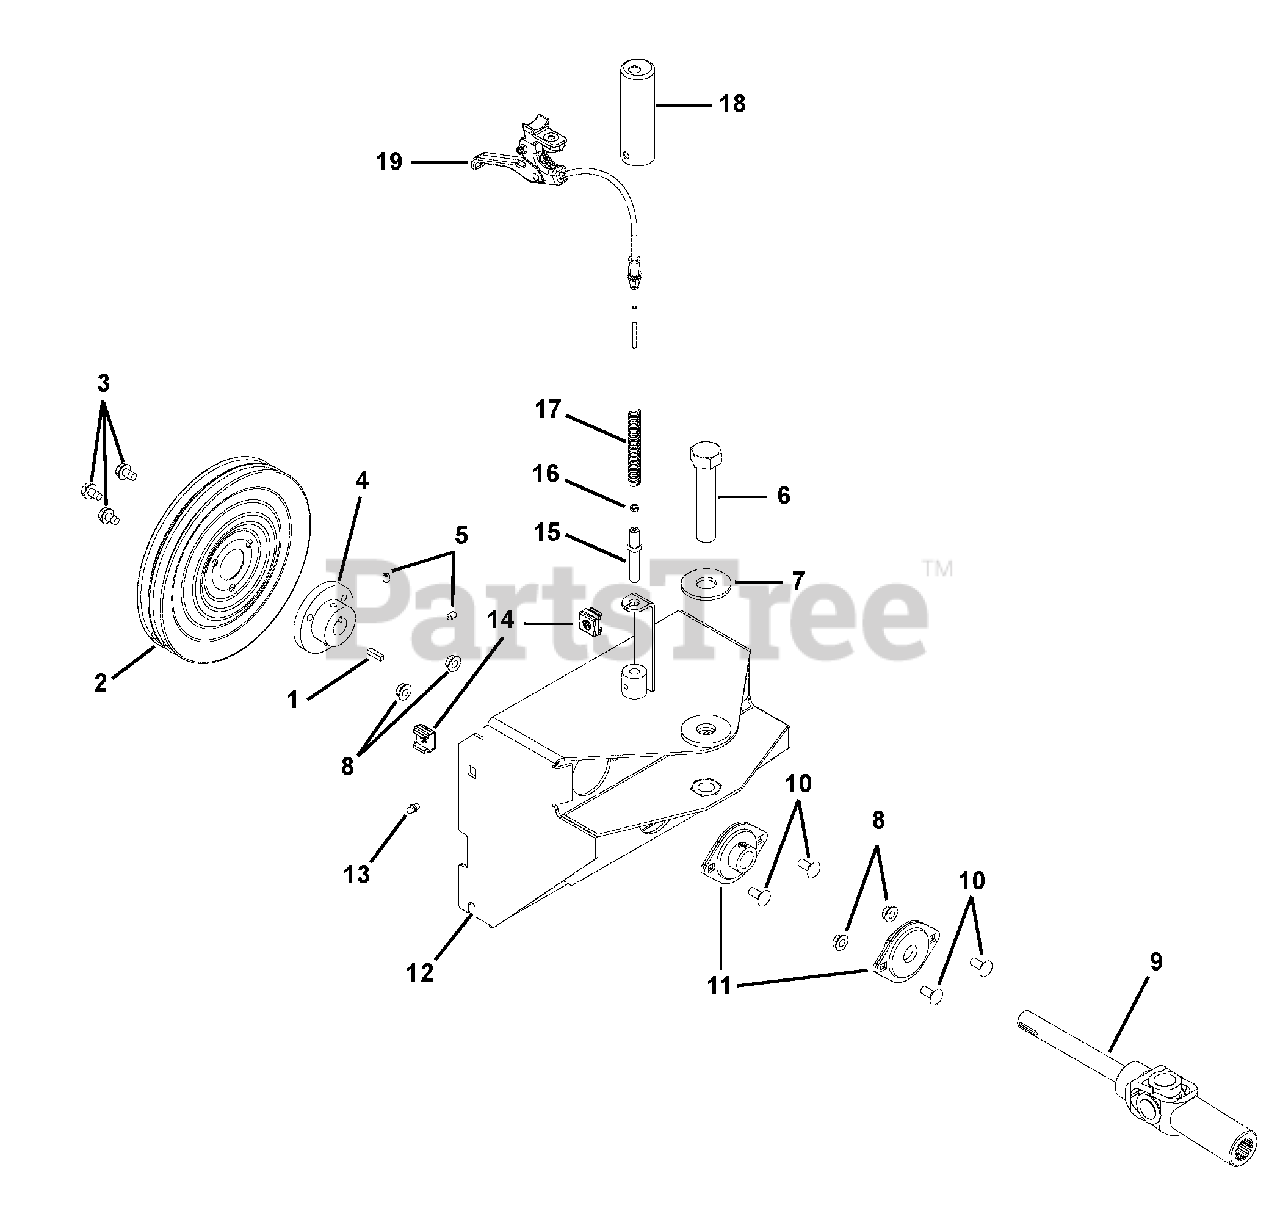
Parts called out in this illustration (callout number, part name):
1	KEY-SQ .188X.75X.188
2	PULLEY, SPIN FORM DUAL GROOVE
3	@SCR-TAP .31-18X.50 HWH TR YWZ
4	HUB, PULLEY
5	SCR-SET .25-20X.38 SKHCUPNL OH
6	HHCS .75-16 UNF X 3.75
7	@WSHR-FL-STL.812X2.00X.148YWZC
8	@NUT-LK-TOP-FLG .31-18 YWZC
9	DRIVELINE, SERIES 07
10	@BLT-RDHDSQNK .31-18X.75 G5YZ
11	BEARING, 3/4" FLANGETTE
12	MTG FRAME, MCD ARIENS
13	FTG-LUBE .25-28X.256 YWZC
14	NUT-RETNR .38-16 TINRMAN
15	PIN, SWING MCD-TRIGGER RELEASE
16	@NUT-HEX 10-24 YWZC
17	SPRING, COMPRESSION .51"X3.5"
18	CAP, VINYL MODIFIED
19	CABLE, REMOTE BRUSH LOCK
